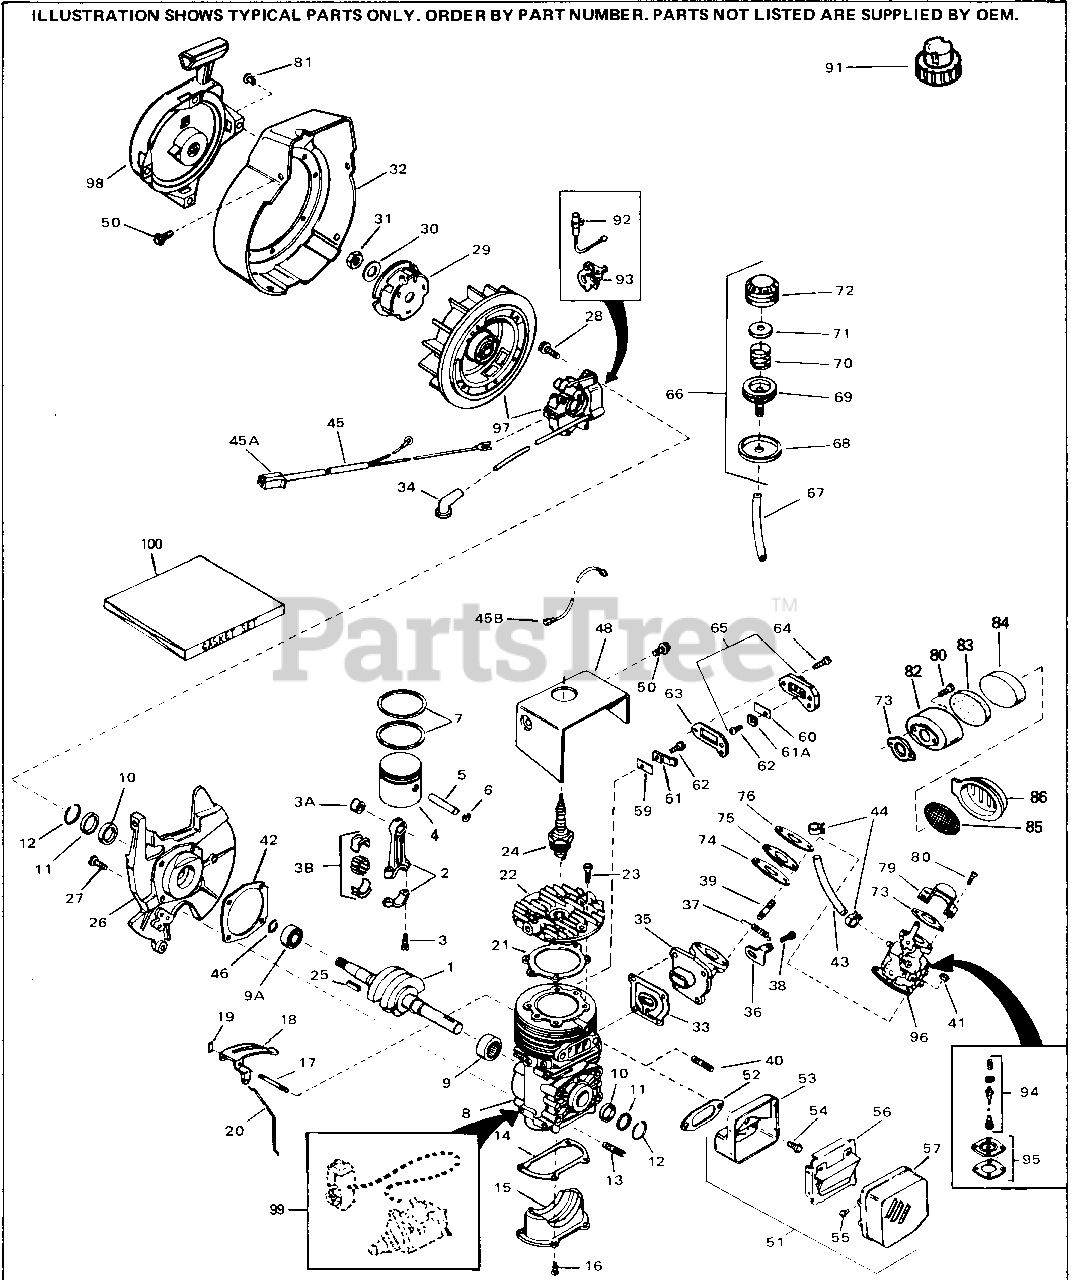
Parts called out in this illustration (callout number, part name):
1	"Crankshaft
3	Screw, Connecting rod
3A	Bearing, Cartridge
3B	Bearing & Liner Set, Needle
4	Piston
5	Pin, Piston
6	Ring, Piston pin retaining
7	Ring Set, Piston
8	Block Assy., Cylinder
9	Bearing, Cartridge
9A	Bearing, Ball
10	Seal, Crankshaft
13	Stud, Mounting
14	Gasket, Cover
15	Plate, Cover
17	Shaft, Air vane
18	Vane Assy., Air
19	Clip, Air vane
20	Link, Governor
21	Gasket, Cylinder head
22	Head, Cylinder
24	Plug, Spark (RJ-18Y or equivalent)
25	Key, Flywheel
26	Base Assy., Blower housing
29	Cup, Starter
31	Nut, Flywheel
32	Housing, Blower
33	Gasket, Port
34	Cover, Spark plug
35	Cover, Adapter
36	Lever, Adjusting
37	Spring, Adjusting lever
38	Screw
39	Stud, Carburetor
41	Nut
42	Gasket, Blower housing base
43	Line, Fuel
44	Clamp, Fuel line
45	Harness, Wire
46	Ring, Retaining
51	Muffler Assy.
52	Gasket, Exhaust
59	Reed, Compression release
60	Reed, Compression release
61	Plate, Reed hold down
61A	Plate, Reed hold down
63	Gasket, Compression release
64	Screw
65	Cover Assy., Compression release
66	Primer Assy.
67	Line, Primer
68	Retainer, Primer bulb
69	Body, Primer
72	Bulb, Primer
73	Gasket
79	Baffle, Air
81	Rivet, Pop (3/16" Dia.)
92	Condenser
93	Contact Assy., Breaker
94	Inlet Needle, Seat, Spring & Gasket A ssy.
95	Diaphragm Assy.
96	Carburetor
98	Starter Assy., Rewind
100	Gasket Set
